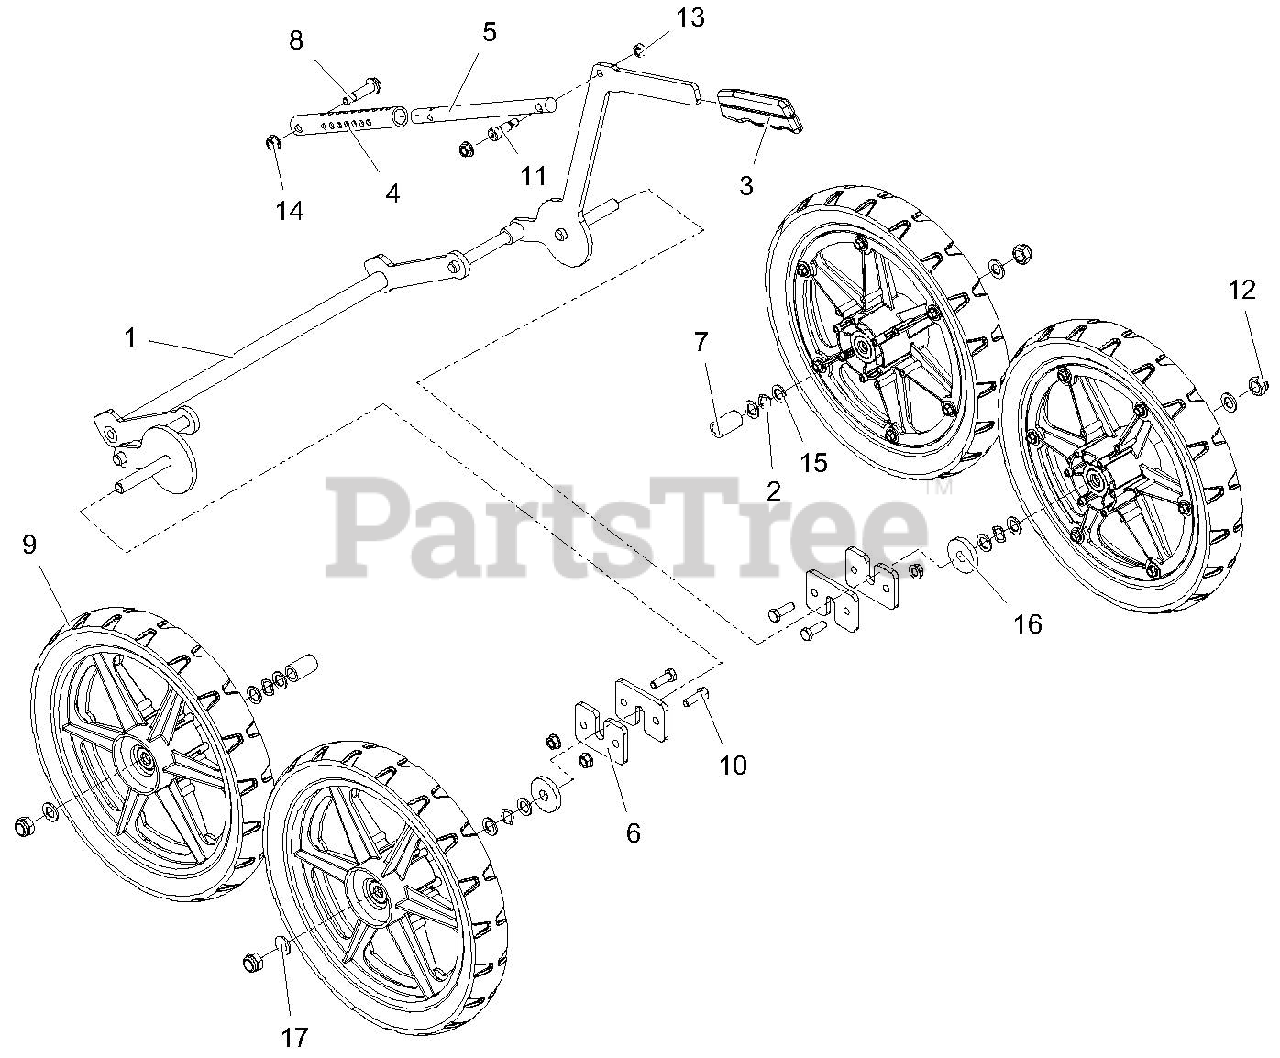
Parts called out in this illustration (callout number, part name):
1	WLDMT, CROSS SHFT - HEIGHT ADJ
2	WAVE WASHER .531X.781X.125FH
3	GRIP, PARKING BRAKE (YELLOW)
4	TUBE, ADJ - APV HEIGHT ADJ
5	ROD, ADJ - APV HEIGHT ADJ
6	PLATE, RETAINER-APV HEIGHT ADJ
7	SPCR, WHEEL - APV REAR WHEEL
8	BLT-SHLDR, .50X1.15X.312-18GR5
9	WHEEL-14X2 .50ID W/DRIVE HUB
10	@BLT-HEX .31-18X1.00 GR5 YWZC
11	BLT,SHLDR-.38DIA X.75EL;.31-18
12	NUT, ACORN - 1/2-13 ELC
13	@NUT-LK-CTR .31-18 YWZC
14	@NUT-LK-TOP-FLG .31-18 YWZC
15	WSHR-FL-STL .52X.827X.062 YWZC
16	WSHR-FL-STL .515X1.625X.250 YZ
17	WSHR-FL-STL .505X.880X.072 YWZ
